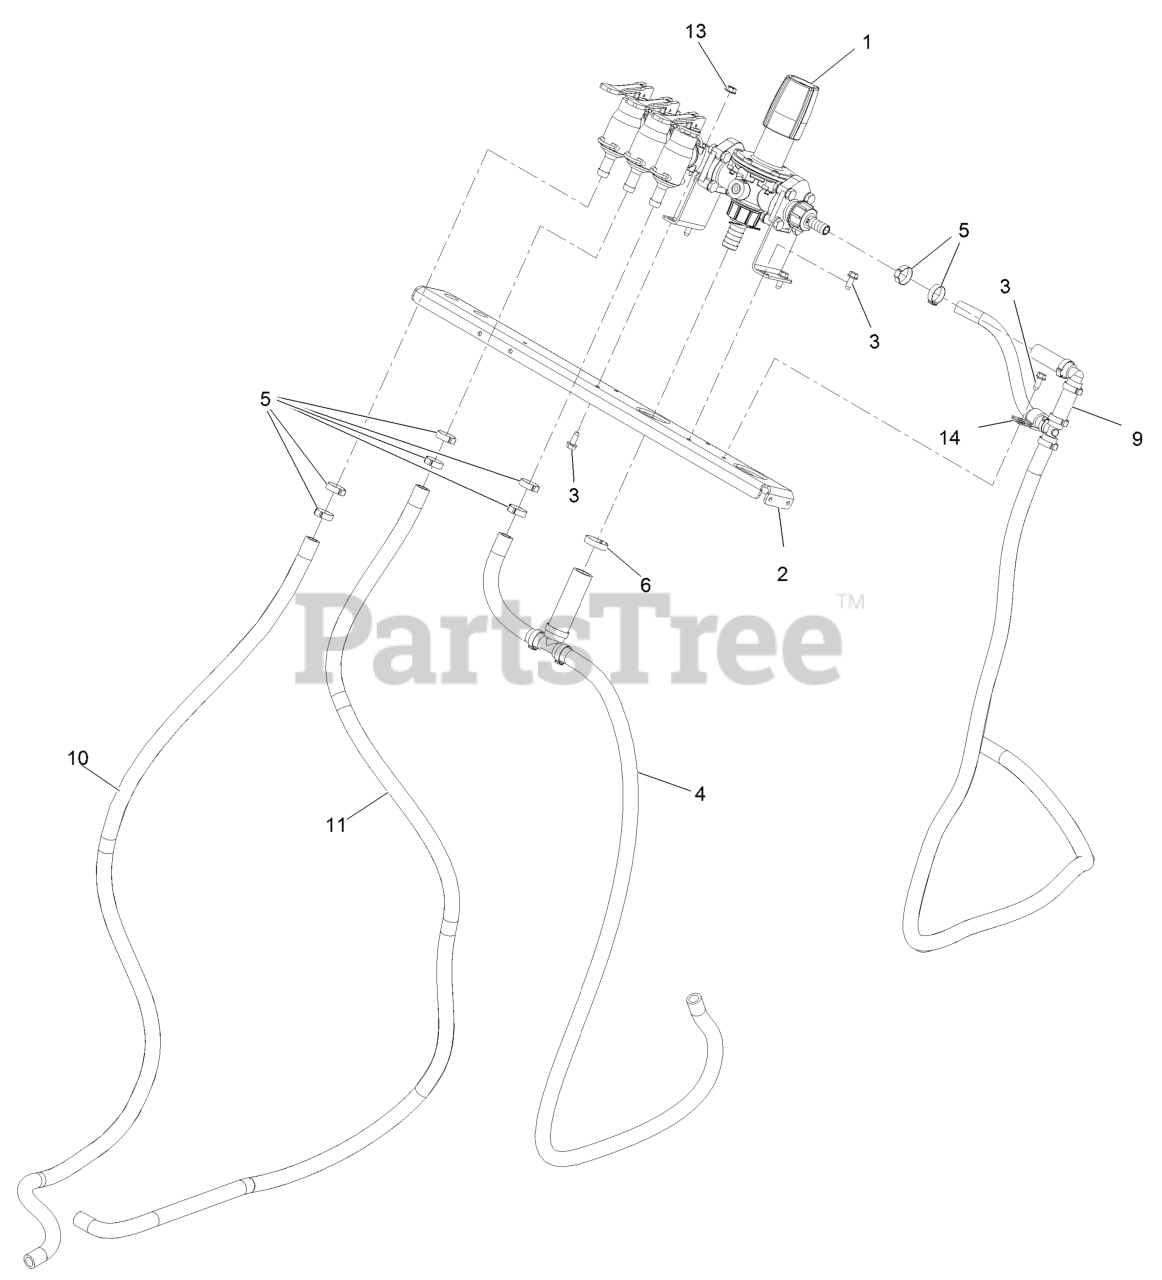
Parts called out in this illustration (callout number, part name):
1	SPRAY MANIFOLD ASSEMBLY
2	CROSSMEMBER-COLUMN
3	SCREW-HWH
4	HOSE ASM
9	HOSE ASM
10	HOSE-WATER
11	HOSE-WATER
14	CLIP-LOOM
